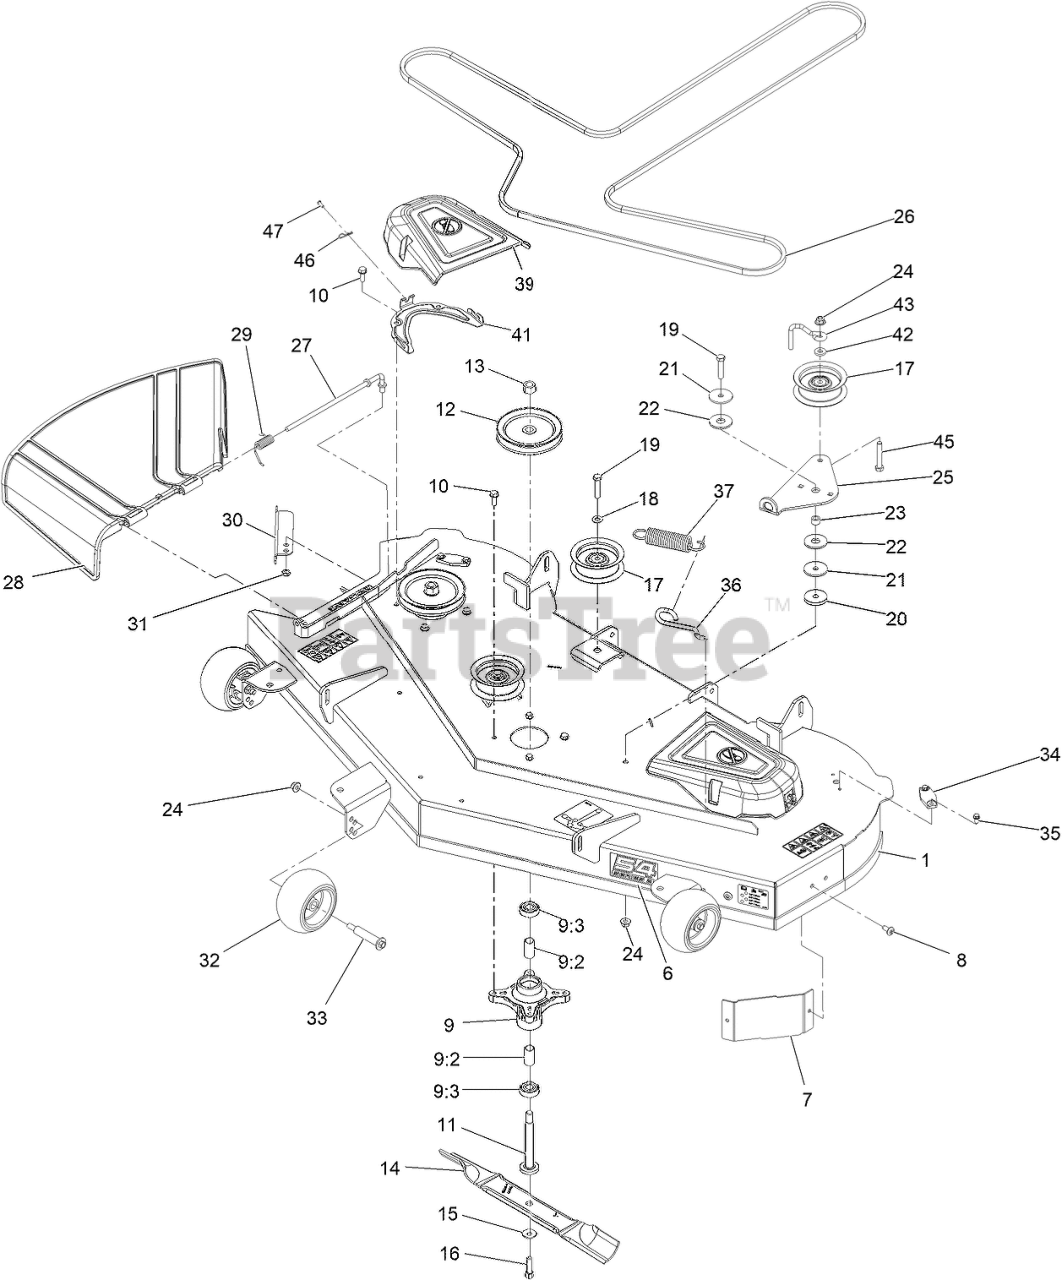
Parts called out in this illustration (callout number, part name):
1	DECK ASM-54 4PT
6	DECAL-54 SERIES 2
7	BAFFLE-CORNER
9	SPINDLE ASM
9:3	BEARING-BALL
10	SCREW-TAPTITE
11	SHAFT-SPINDLE
12	PULLEY ASM
13	NUT-HEX
14	BLADE-HI LIFT
15	WASHER-BELLEVILLE
16	SCREW-HH
17	PULLEY-IDLER, FLAT
18	WASHER-FLAT
19	SCREW-HH
20	WASHER-PLAIN
21	WASHER-REBOUND
22	WASHER-FRICTION, COMPOSIT
24	NUT-HF, NI
25	Arm-Idler
26	BELT-V
27	ROD-PIVOT
28	DEFLECTOR-DISCHARGE
29	SPRING-TORSION
30	BAFFLE-CUTOFF
32	ROLLER-SCALP, ANTI
33	BOLT-SHOULDER
34	COVER-WASHOUT PORT
35	SCREW-HWH
36	Hook-Return Spring
37	SPRING-EXTENSION
39	COVER-BELT
41	BRACKET-COVER, BELT
42	SPACER-HUB, BLOWER
43	Belt Guide - Idler
45	SCREW-HH
46	PIN-HAIR
